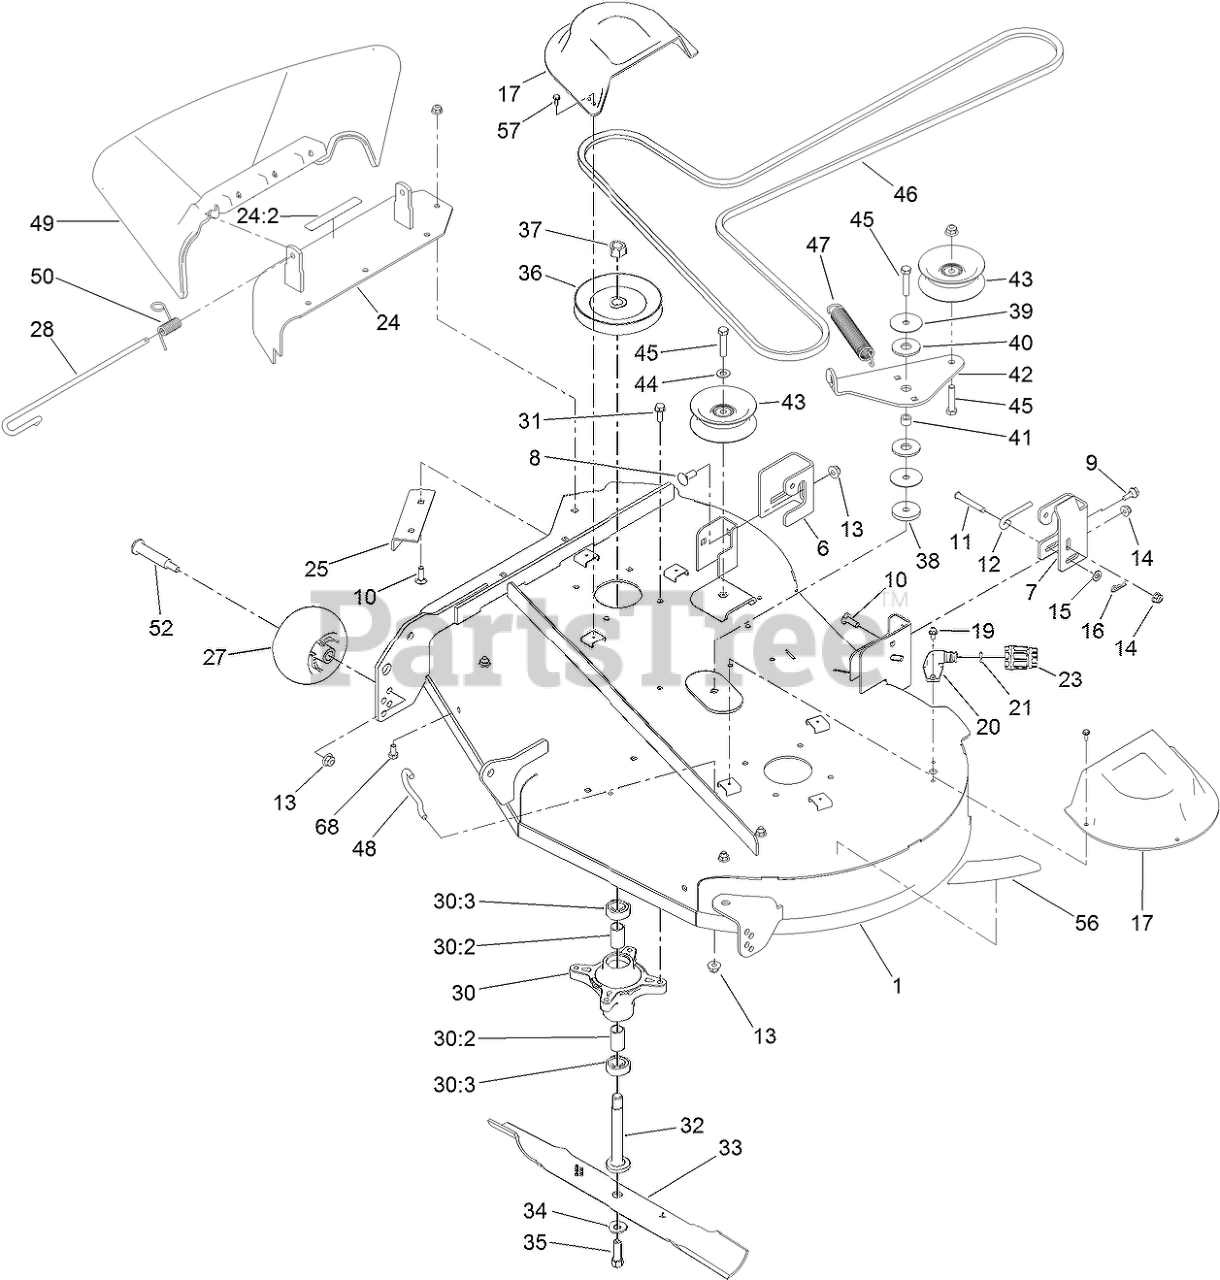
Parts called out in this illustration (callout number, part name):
1	42 INCH DECK ASM
6	BRACKET-HANGER, RH
7	BRACKET-HANGER, LH
8	BOLT-CARR
9	SCREW-SHOULDER, HHF
10	SCREW-CARR
11	PIN-CLEVIS
12	ROD-LEVEL, DECK
13	NUT-HF, NI
14	NUT-HF, NI
15	WASHER-PLAIN
16	PIN-COTTER
17	COVER-BELT
19	SCREW-HWH
20	FITTING-WASHOUT
21	O-RING
23	CONNECTOR-HOSE
24	COVER ASM W/DECAL
24:2	DECAL-DANGER
25	BAFFLE-CUTOFF
27	ROLLER-SCALP, ANTI
28	PIN-CHUTE
30	SPINDLE ASM
30:2	SPACER
30:3	BEARING-BALL
31	SCREW-TAPTITE
32	SHAFT-SPINDLE
33	BLADE-HIGH LIFT
34	WASHER-BELLEVILLE
35	SCREW-HH
36	Pulley
37	NUT-HEX
38	WASHER-PLAIN
39	WASHER
40	WASHER-FRICTION, COMPOSITE
41	SPACER
42	ARM-IDLER
43	PULLEY-IDLER, FLAT
44	WASHER-FLAT
45	SCREW-HH
46	V-BELT
47	SPRING-EXTENSION
48	HOOK-RETURN, SPRING
49	DEFLECTOR-DISCHARGE
50	SPRING-TORSION
52	BOLT-SHOULDER
56	DECAL-DECK
57	SCREW-TAPTITE
68	SCREW-HH
